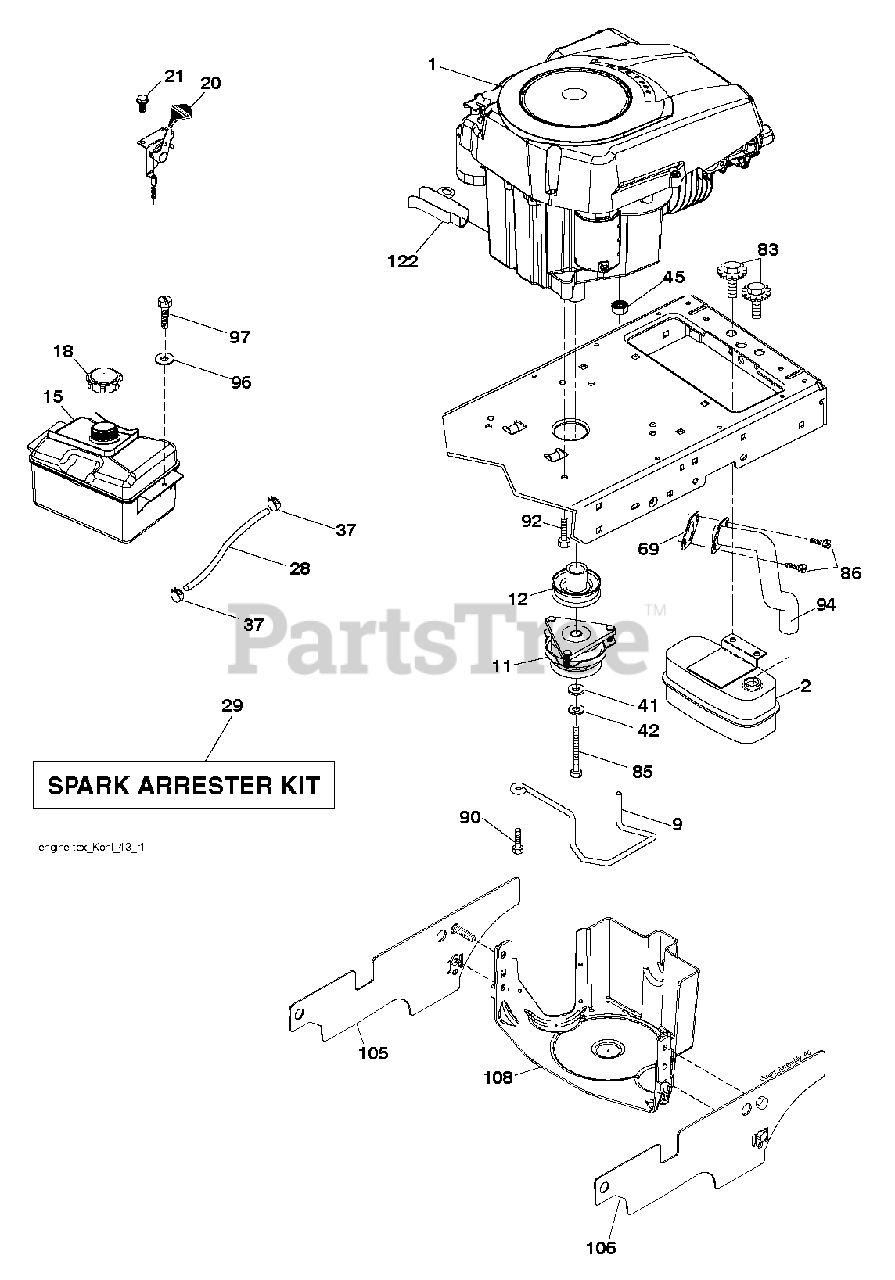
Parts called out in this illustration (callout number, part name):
2	MUFFLER.SINGLE.CYL.KOHL/B&S
9	KEEPER.BELT.ENGINE.4.2
11	RB.CLUTCH.OGURA.4.4.PD
12	PULLEY.ENGINE.TUFFTORQ
15	RP TANK FUEL FRT 1.5 GAL
18	CAP ASM.FUEL.2.25"FR.
20	CONTROL.TH/CK.C.
21	SCREW.#10 X 0.750.BOS
28	LINE.FUEL.20
29	KIT.SPARK ARRESTOR 794945 B&S
37	HOSE CLAMP
42	LOCKWASHER
45	NUT
69	REPL BY 532 27 22-93
83	BOLT, 5/16-18 X 1 3/4
85	BOLT HEX 7/16-20X4-1/4"
86	SCREW.SOCKET HD.5/16-1
90	SCREW 3/8-16X1
92	SCREW 3/8-16X1
94	EXHAUST.TUBE.B&S.
97	SCREW HEXWSHR 1/4-20X3/4
108	ENGINE COVER
122	EXTENSION DRAIN OIL
